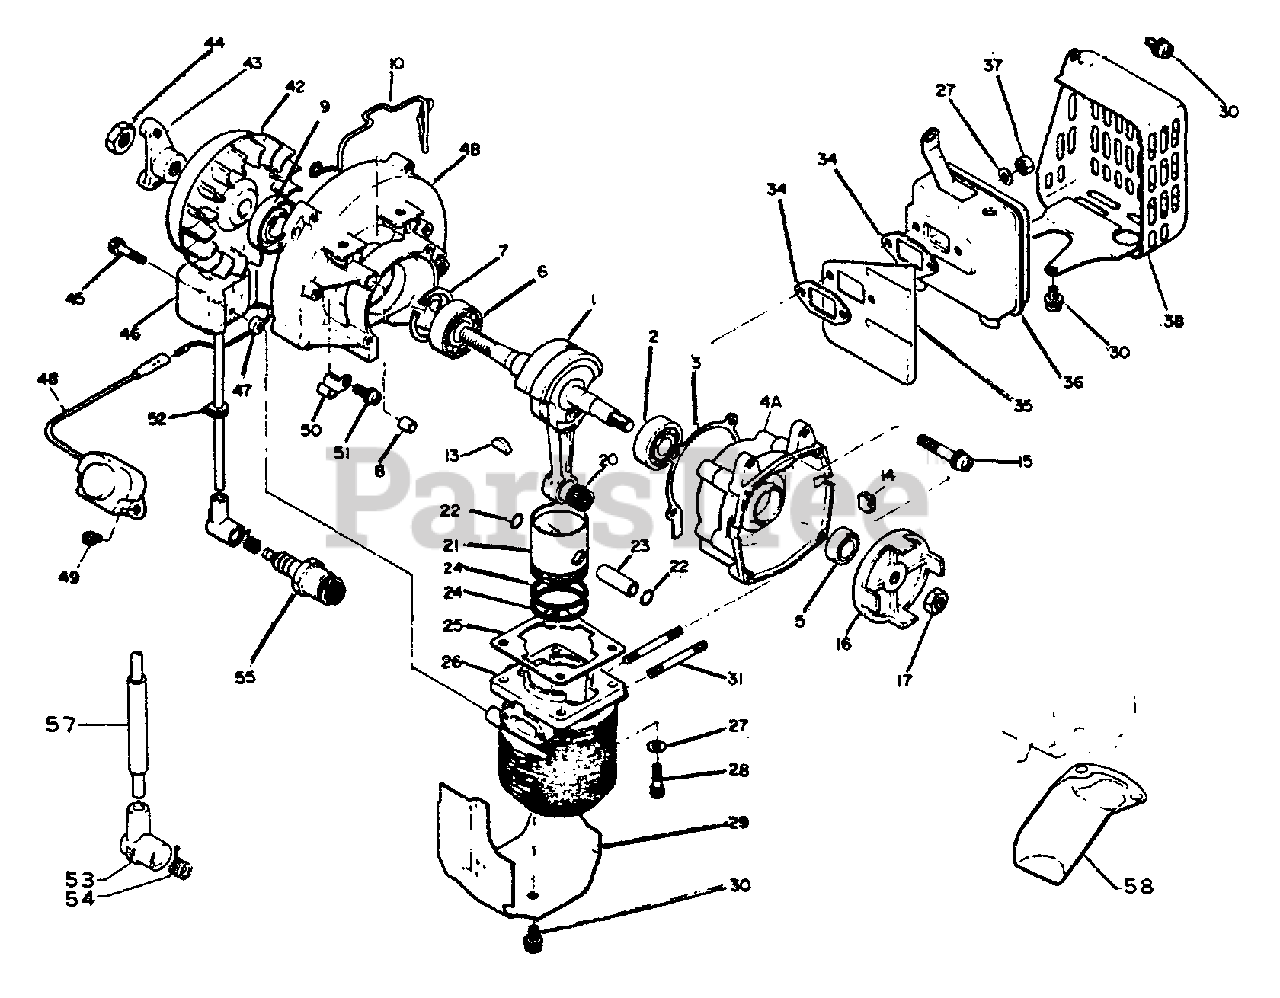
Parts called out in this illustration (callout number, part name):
1	CRANKSHAFT ASSY
2	BEARING, BALL - 6201 C3
3	GASKET, CRANKCASE
5	SEAL, OIL
6	BEARING, BALL 6202
7	RING, SNAP 35
8	PIN, DOWEL
9	SEAL, OIL
10	BUMPER
14	PLUG
15	SCREW 5×35
16	CATCHER, PAWL
17	NUT 8×1.25
20	BEARING, NEEDLE
21	PISTON
22	RING, SNAP 8
23	PIN, PISTON
24	RING, PISTON
25	GASKET, CYLINDER
26	CYLINDER
27	WASHER, FLAT 5.5×10×0.8
28	BOLT 5×20
29	SHIELD, CYLINDER
30	SCREW 5×10
31	STUD
34	GASKET, EXHAUST
35	COVER, MUFFLER
36	MUFFLER
37	LOCKNUT - 5
38	COVER, MUFFLER
42	FLYWHEEL
43	HUB, CLUTCH
44	NUT 10×1.25
45	SCREW 5×22
46	COIL, IGNITION
47	SPACER
48	COIL, IGNITION
49	SCREW - 5×6
50	CLIP
51	SCREW 5×12
53	CAP, SPARK PLUG
54	TERMINAL, SPARK PLUG
55	SPARK PLUG - BM6A
57	PIPE
